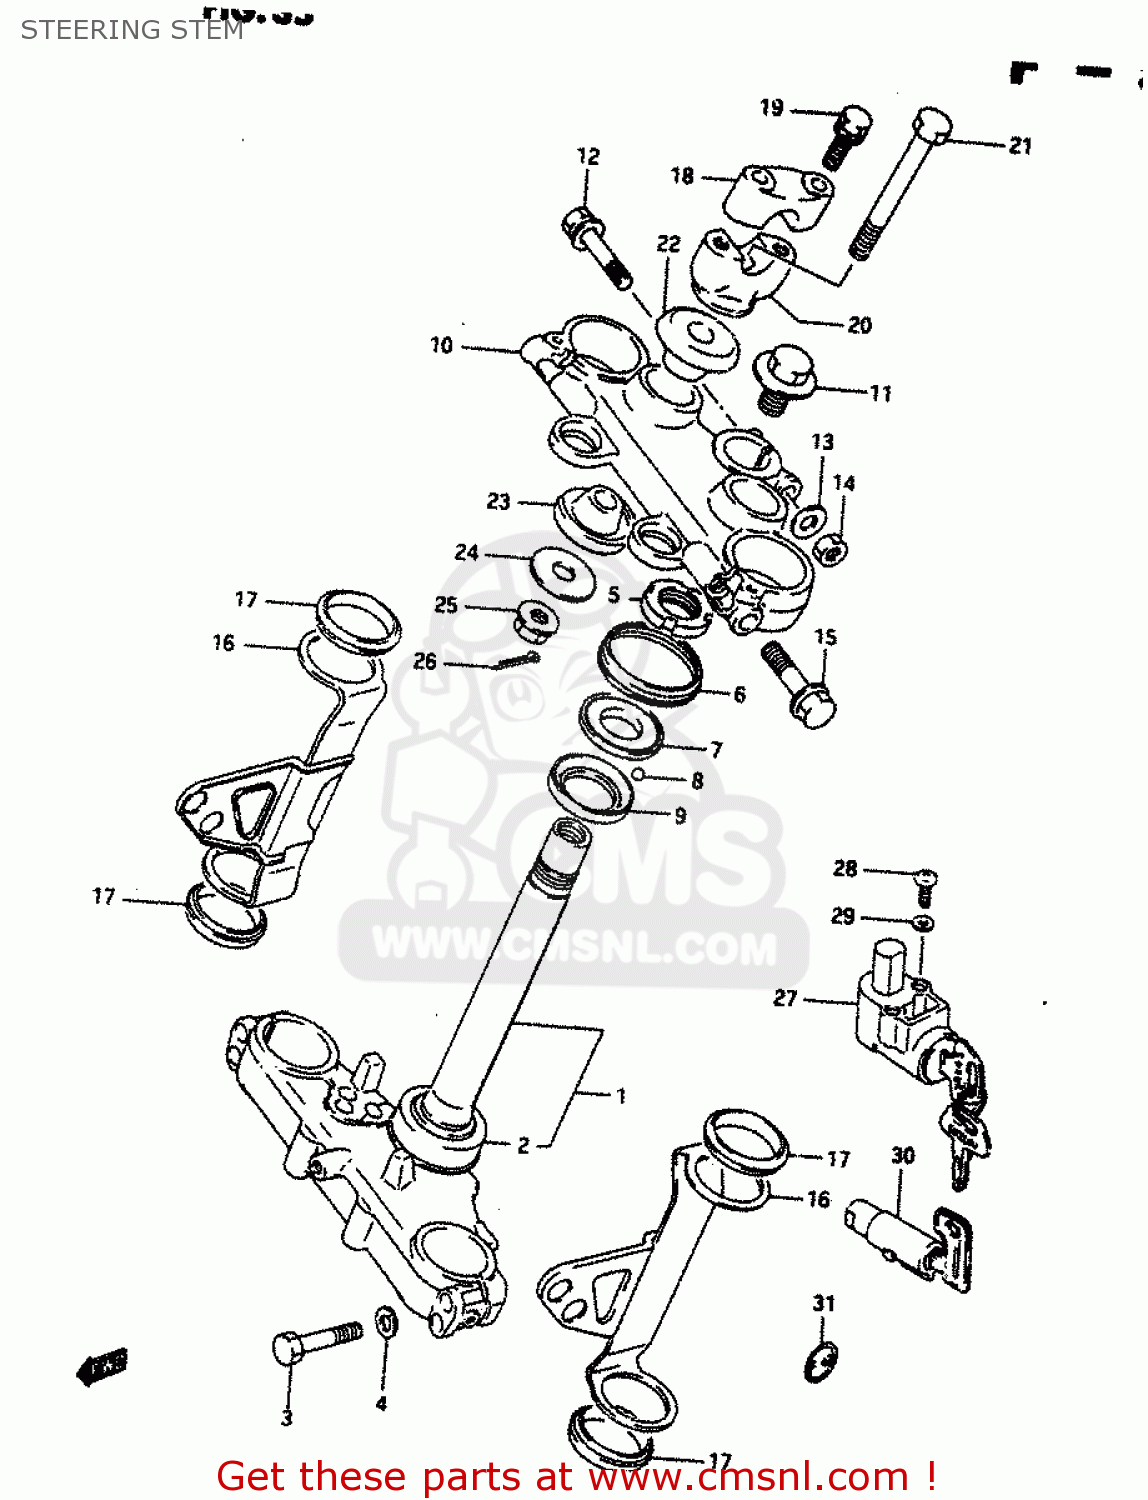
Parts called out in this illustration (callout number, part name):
1	STEM,STEERING
2	BEARING(30X55X17)
3	BOLT
4	LOCK WASHER
5	NUT,STEERING STEM
6	SEAL,STEERING UPR DUST
7	RACE,STEERING,OUTER,UPPER
8	BALL
9	RACE,STEERING INNER (SUJ)
10	HEAD,STEERING STEM
11	BOLT,STEERING STEM
12	BOLT
13	WASHER
14	NUT ,8MM
15	BOLT
16	COVER,FORK,LEFT
17	CUSHION,HEADLAMP BRACKET
18	HOLDER,HANDLEBAR
19	BOLT
20	HOLDER,HANDLE LWR
21	BOLT,HANDLE HOLDER
22	DAMPER,UPR
23	DAMPER,LWR
24	WASHER,HANDLEBAR HOLDER
25	NUT
26	COTTER PIN
27	LOCK ASSY,STEERING
28	SCREW
29	LOCK WASHER
30	LOCK ASSY,STEERING(NEIMAN)
31	LABEL,STEERING LOCK
